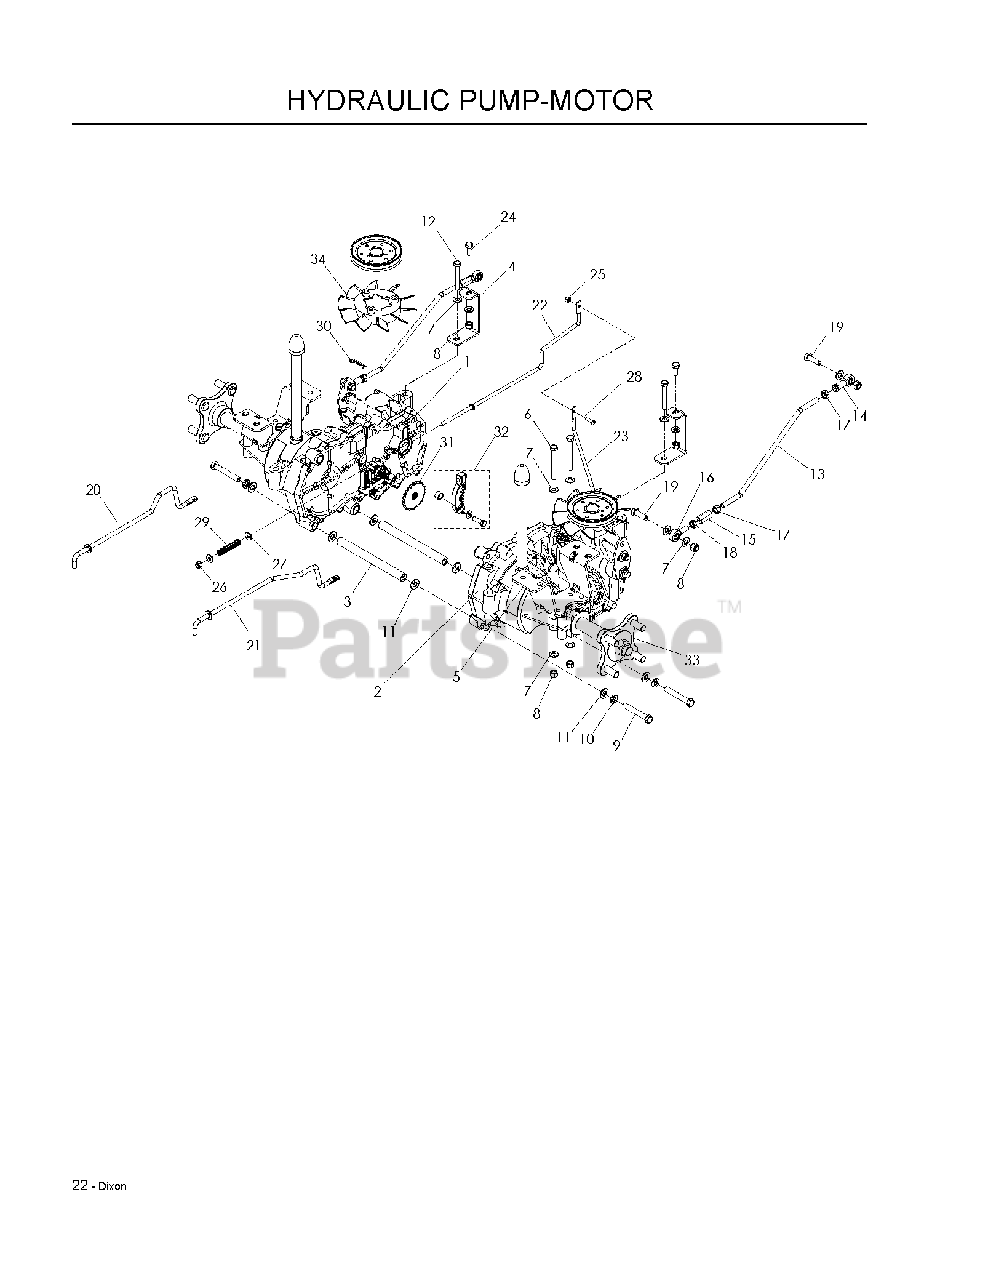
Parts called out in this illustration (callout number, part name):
1	HG_EZT, LT
2	HG_EZT, RT
3	SPACER TUBE, EZT
4	SUPPORT.FRONT.TRANS.BLACK.
5	EZT MOUNT, REAR, BLACK
6	HCS 5/16C X 2-3/4
7	FLAT WASHER 5/16 SAE
8	NUT 5/16 NYLOC
9	HCS 3/8C X 2 1/2
10	SLW 3/8 STD
11	WASHER 3/8 SAE FLAT
12	CAPSCREW
13	ROD, MOTION CONTROL
14	RH ROD END
15	ROD END COUPLER
16	ROD.END.LH
17	NUT 5/16F
18	NUT 5/16F LEFTHAND
19	HCS 5/16C X 1
20	ROD, BYPASS, RT
21	ROD, BYPASS, LT
22	LINKAGE BRAKE LT
23	LINKAGE BRAKE RT
24	HCS 5/16C X 3/4
25	NUT 10-24 NYLOC
26	NUT 1/4-20 NYLOC
27	WASHER 1/4 SAE
28	SCR #10-24 X 3/4
30	HAIRPIN #2
31	HG_DISC COG BRAKE
32	HG_KIT BRAKE ARM (EZT)
33	HUB KIT (H-G #70314)
34	HG_HYDRO FAN
